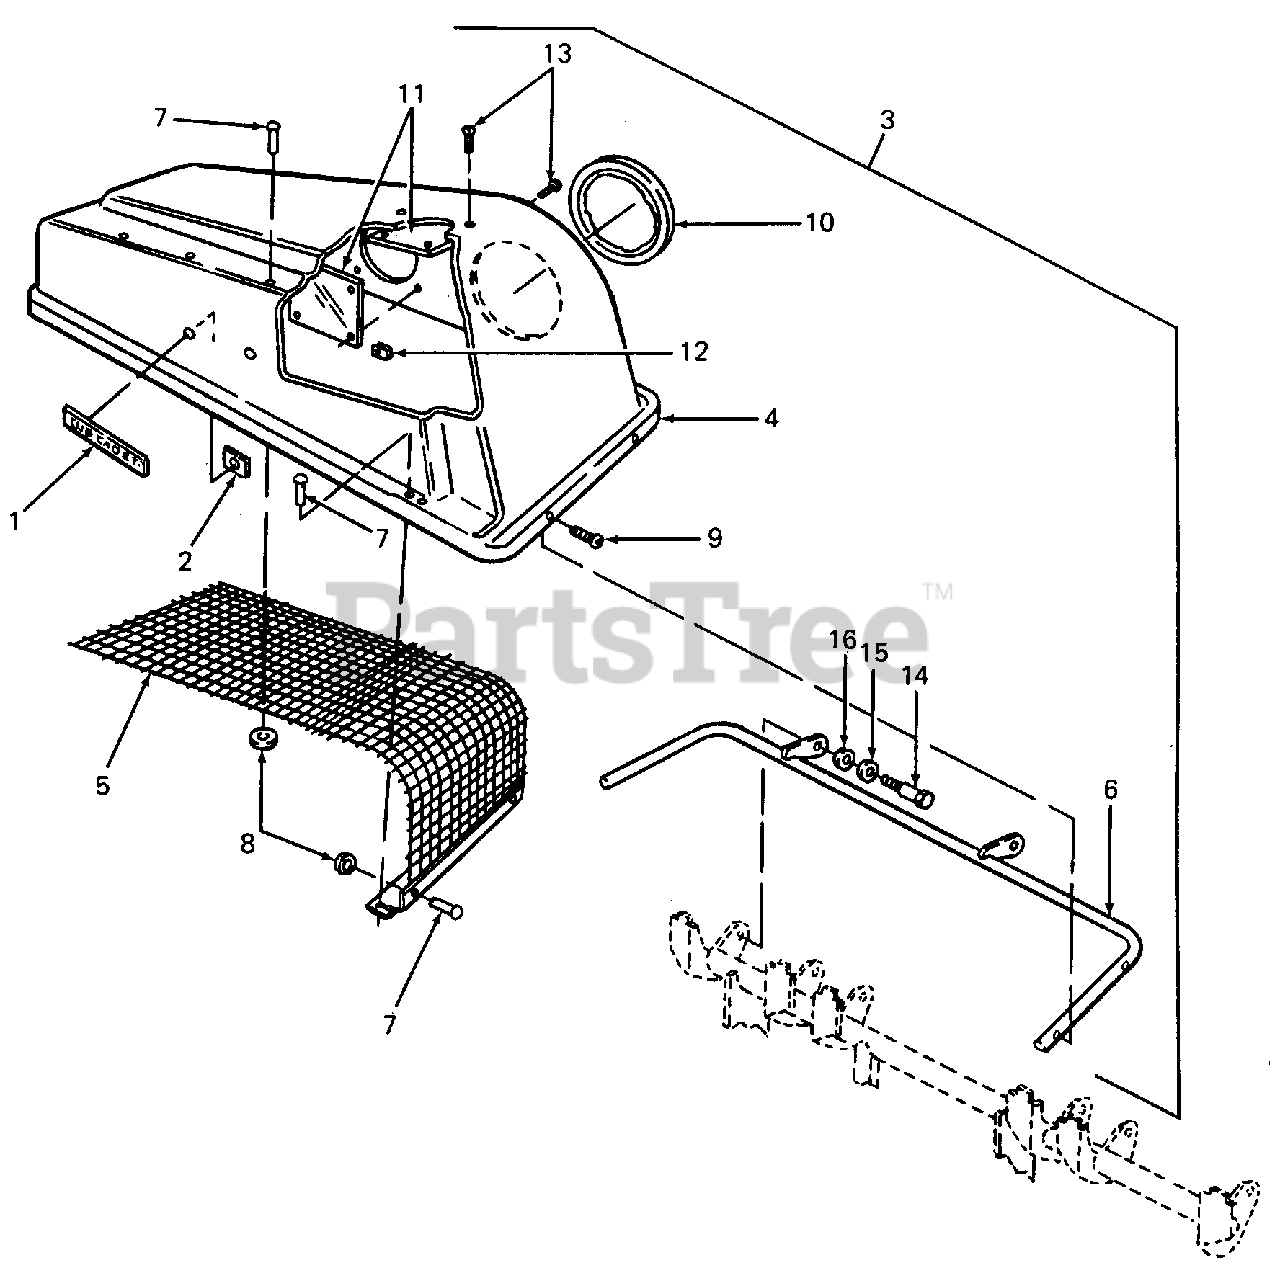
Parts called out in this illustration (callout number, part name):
1	Plaque, Logo w/Studs
2	Nut, Push-on Speed
3	Cover Assy, Grass Catcher
8	Washer, Flat, .218 X .62 X .063
9	Screw, Hex Wash. Hd. Tapp, 1/4 X .50 Lg
10	Seal, Tube, 8.1 ID
11	Plate, Plastic, 1/8 Thk X 5.62 Sq
12	Nut, U-Type Speed
13	Screw, Truss Mach., #10 X .50 Lg
14	Screw, Shld
15	Washer, Flat, .510 X .75 X .033
16	Washer, Bell, .515 X 1.14
